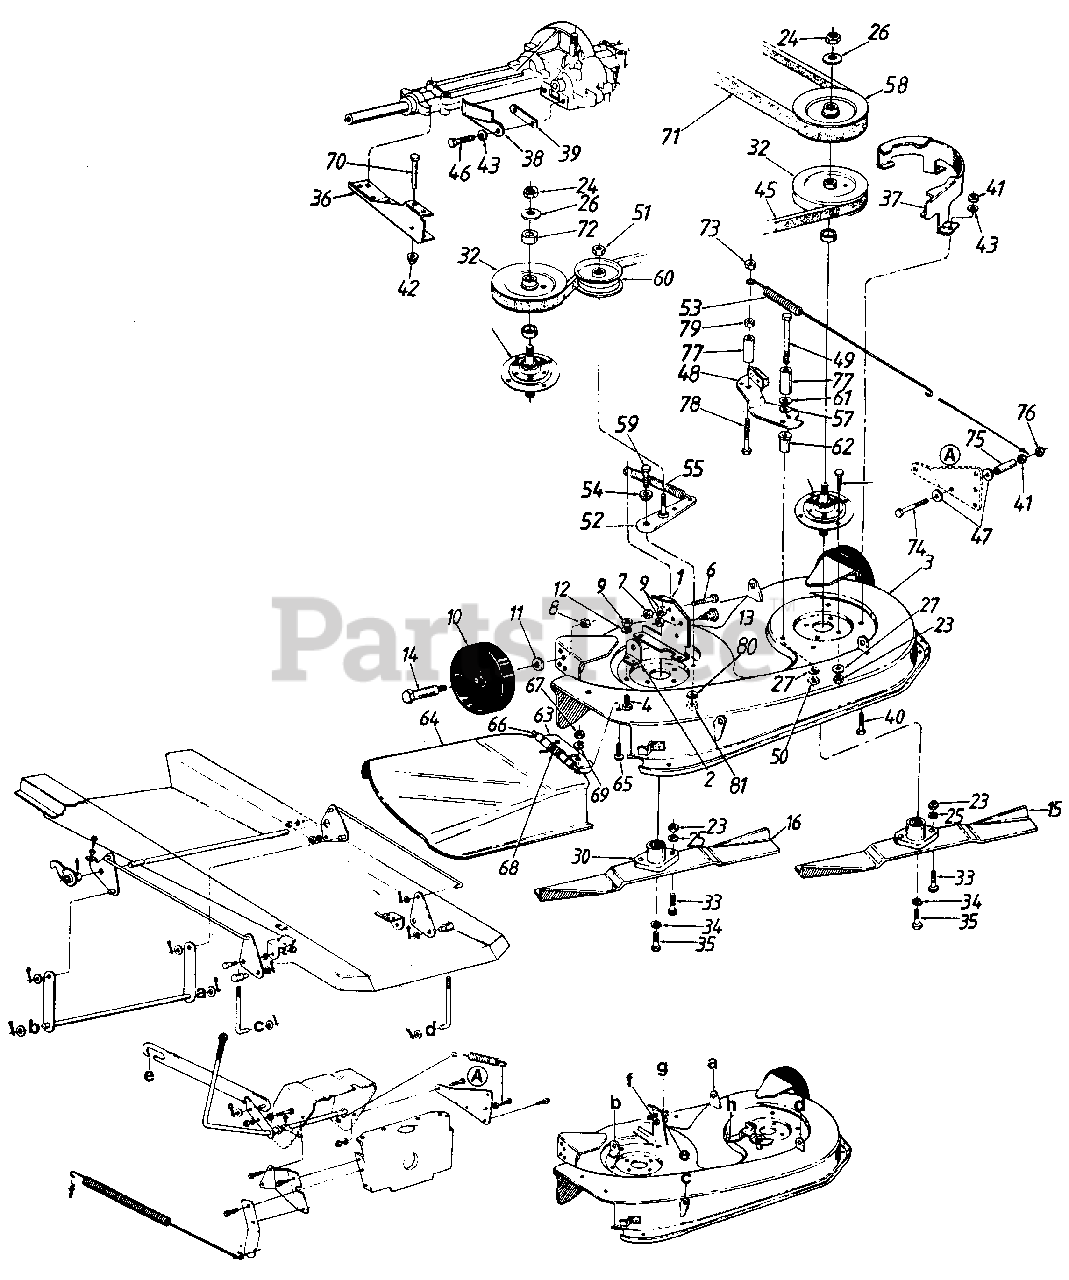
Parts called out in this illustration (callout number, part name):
1	Deck Disengagement Brkt.
2	Rear Deck Brkt.-R.H.
3	38" Deck Ass'y.
4	Hex Bolt 1/4-20 x .62" Lg.
6	Hex Wash. Hd. Scr. 1/4-20 x 1.5" Lg.
7	Hex L-Nut 1/4-20 Thd.
8	Hex L-Nut 3/8-16 Thd.
9	Hex Nut 1/4-20 Thd.
10	Deck Wheel
11	Bell-Wash. .380 I.D. x .88
12	L-Wash 1/4 1. D .
13	Shld Bolt .500 Dia. x .215" Lg.
14	Shld Bolt .498 Dia. x 1.53" Lg.
15	L.H High-Lift Blade
16	R.H. High-Lift Blade
23	Hex Nut 5/16-24 Thd.
24	Hex Jam Nut 5/8-18 Thd.
25	L-Wash. 5/16" I.D.
26	L-Wash. 5/8" I.D.
27	Bell-Wash. .345 I.D. x .88
30	Blade Adapter
32	5" Dia. Pulley (1" Hub)
33	Hex Bolt 5/16-24 x 1.0" Lg. (Special)
34	L-Wash. 3/8" I.D. H.D.
35	Hex Bolt 3/8-24 x 1.0" Lg.
36	Lower Outside Belt Guard
37	Belt Guard Deck-R.H.
38	Lower Inside Belt Guard
39	Belt Guard Spacer
40	Hex Bolt 1/4-20 x .62" Lg.
41	Hex Nut 1/4-20 Thd.
42	Speed Nut 1/4" Rod
43	L-Wash. 1/4" I.D.
45	V-Belt
46	Hex Bolt 1/4-20 x .75" Lg.
47	Fl-Wash. 1/4" I.D.
48	Deck Brake Brkt. Ass'y.
49	Hex Bolt 5/16-18 x 3.25" Lg.
50	Hex Nut 5/16-18 Thd.
51	Hex L-Nut 3/8-24 Thd.
52	Idler Brkt. Ass'y.
53	Extension Spring 16-3/4" Lg.
54	Shoulder Spacer
55	Extension Spring 7-3/4" Lg.
57	Wave Washer
58	5" Dia. Pulley (3/4" Hub)
59	Hex Bolt 3/8-16 x 1" Lg.
60	Flat Idler Pulley
61	Shld. Spacer.27" Lg.
62	Spacer 1.46" Lg.
63	Chute Brkt.
64	Chute
65	Truss-Mach. Scr. 1/4-20 x .75" Lg.
66	Hinge Pin
67	Hex Nut 1/4-20 Thd.
68	Torsion Spring 1.14" Lg.
69	L-Wash. 1/4" I.D.
71	V-Belt
73	Hex L-Nut 1/4-28 Thd.
74	Hex Bolt 1/4-20 x 2.5" Lg.
75	Spacer 1/4" I.D. x 3/8" O.D.
76	Hex L-Nut 1/4-20 Thd.
77	Spacer 5/16" I.D. x 1/2" O.D.
78	Hex Bolt 1/4-28 x 1.75" Lg.
79	Hex Nut 1/4-28 Thd.*
80	L-Wash. 3/8" I.D.
81	Hex Nut 3/8-16 Thd.
